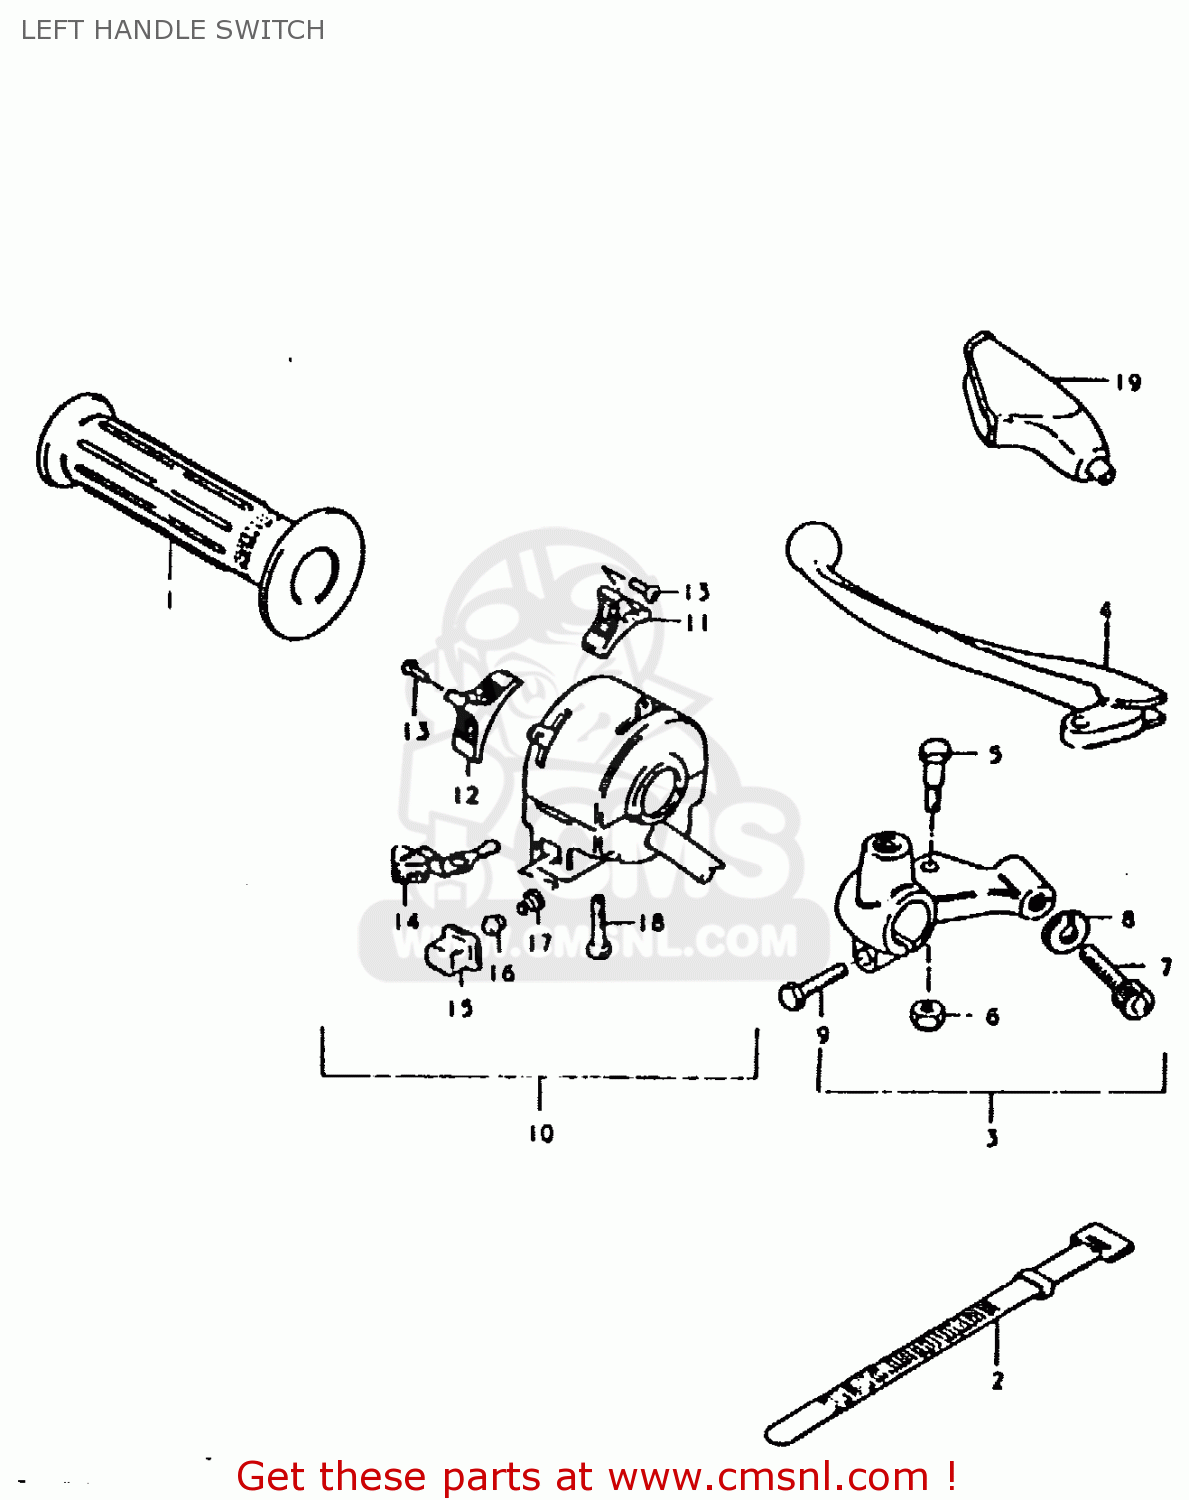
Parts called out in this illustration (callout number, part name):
1	GRIP,L
2	CLAMP(L:120)
3	LEVER ASSEMBLY,CLUTCH
4	LEVER,CLUTCH
5	BOLT,LEVER
6	NUT 6MM
7	ADJUSTER,CABLE
8	NUT,CABLE ADJUSTER
9	BOLT
10	SWITCH ASSY,HANDLE,L
11	KNOB,LIGHTING SWITCH
12	KNOB,DIMMER SWITCH
13	SCREW
14	KNOB,TURNSIGNAL
15	BUTTON,HORN
16	CONTACT
17	SPRING
18	SCREW
19	COVER,CLUTCH LEVER
